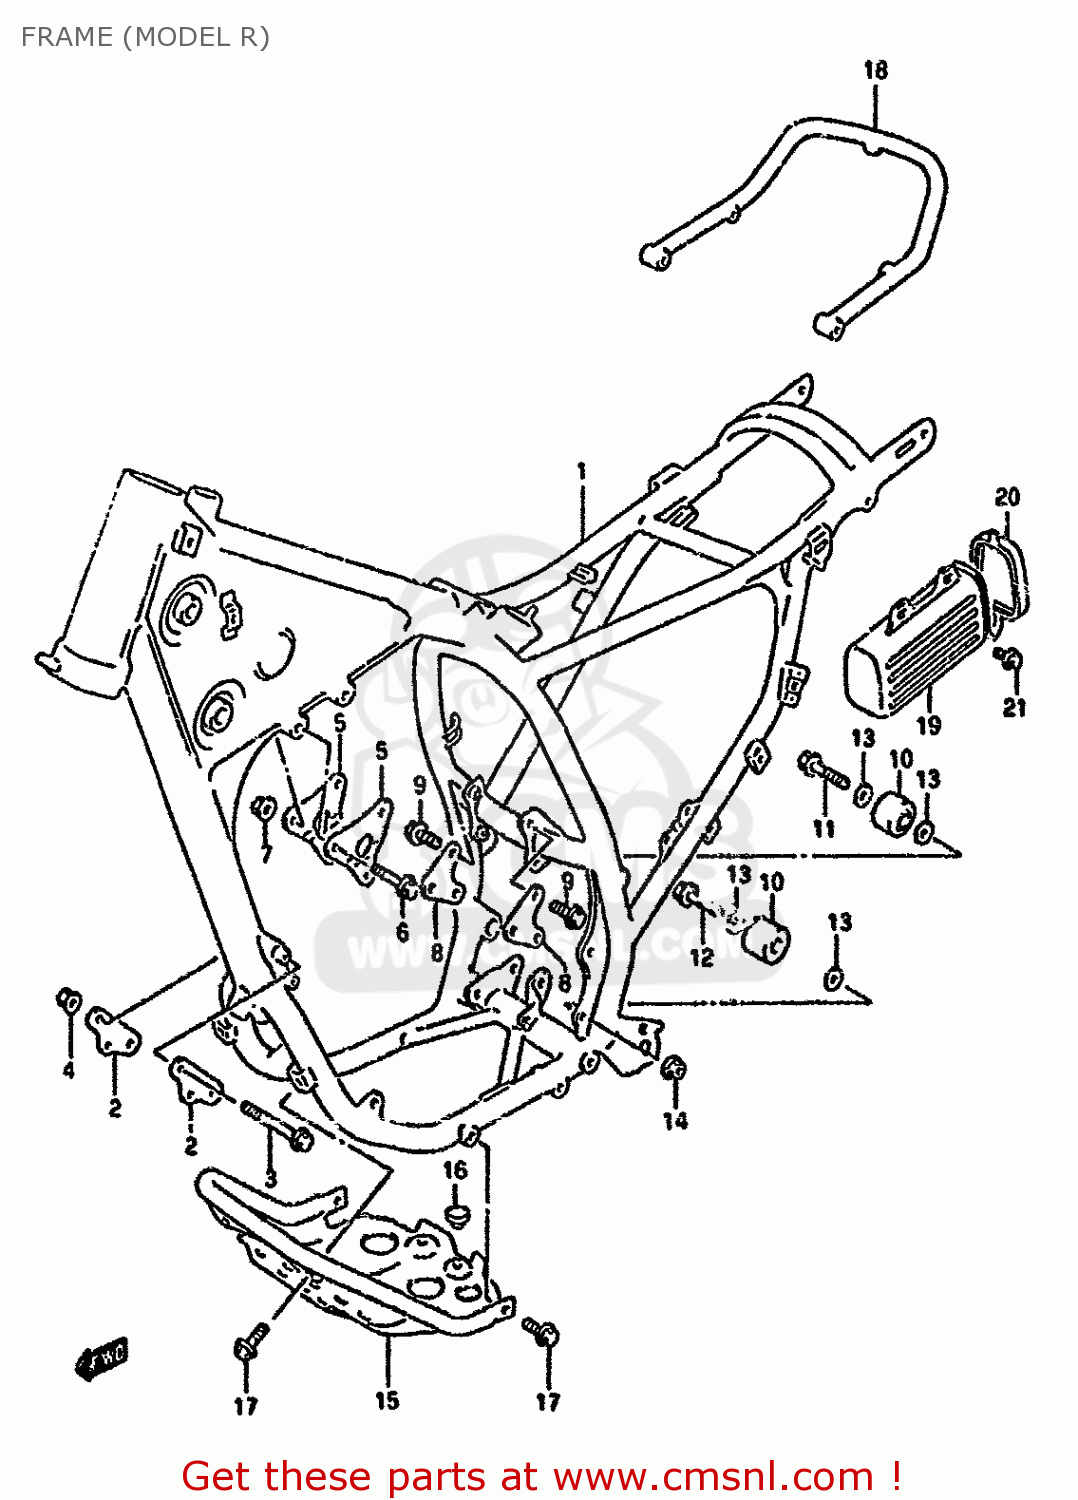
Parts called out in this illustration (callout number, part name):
1	FRAME (BLUE)
2	PLATE,ENGINE MOUNT FR
3	BOLT(8X85)
4	NUT
5	PLATE,ENGINE MOUNT UPR
6	BOLT(8X70)
7	NUT
8	PLATE,ENGINE MOUNTING,REAR
9	BOLT(8X16)
10	ROLLER,CHAIN
11	BOLT(8X38)
12	BOLT 8X45
13	WASHER
14	NUT
15	PROTECTOR,ENGINE(SILVER)
16	CUSHION
17	BOLT
18	GRIP,REAR (WHITE)
19	HOLDER,TOOL
20	CAP,TOOL HOLDER
21	BOLT 6X16
